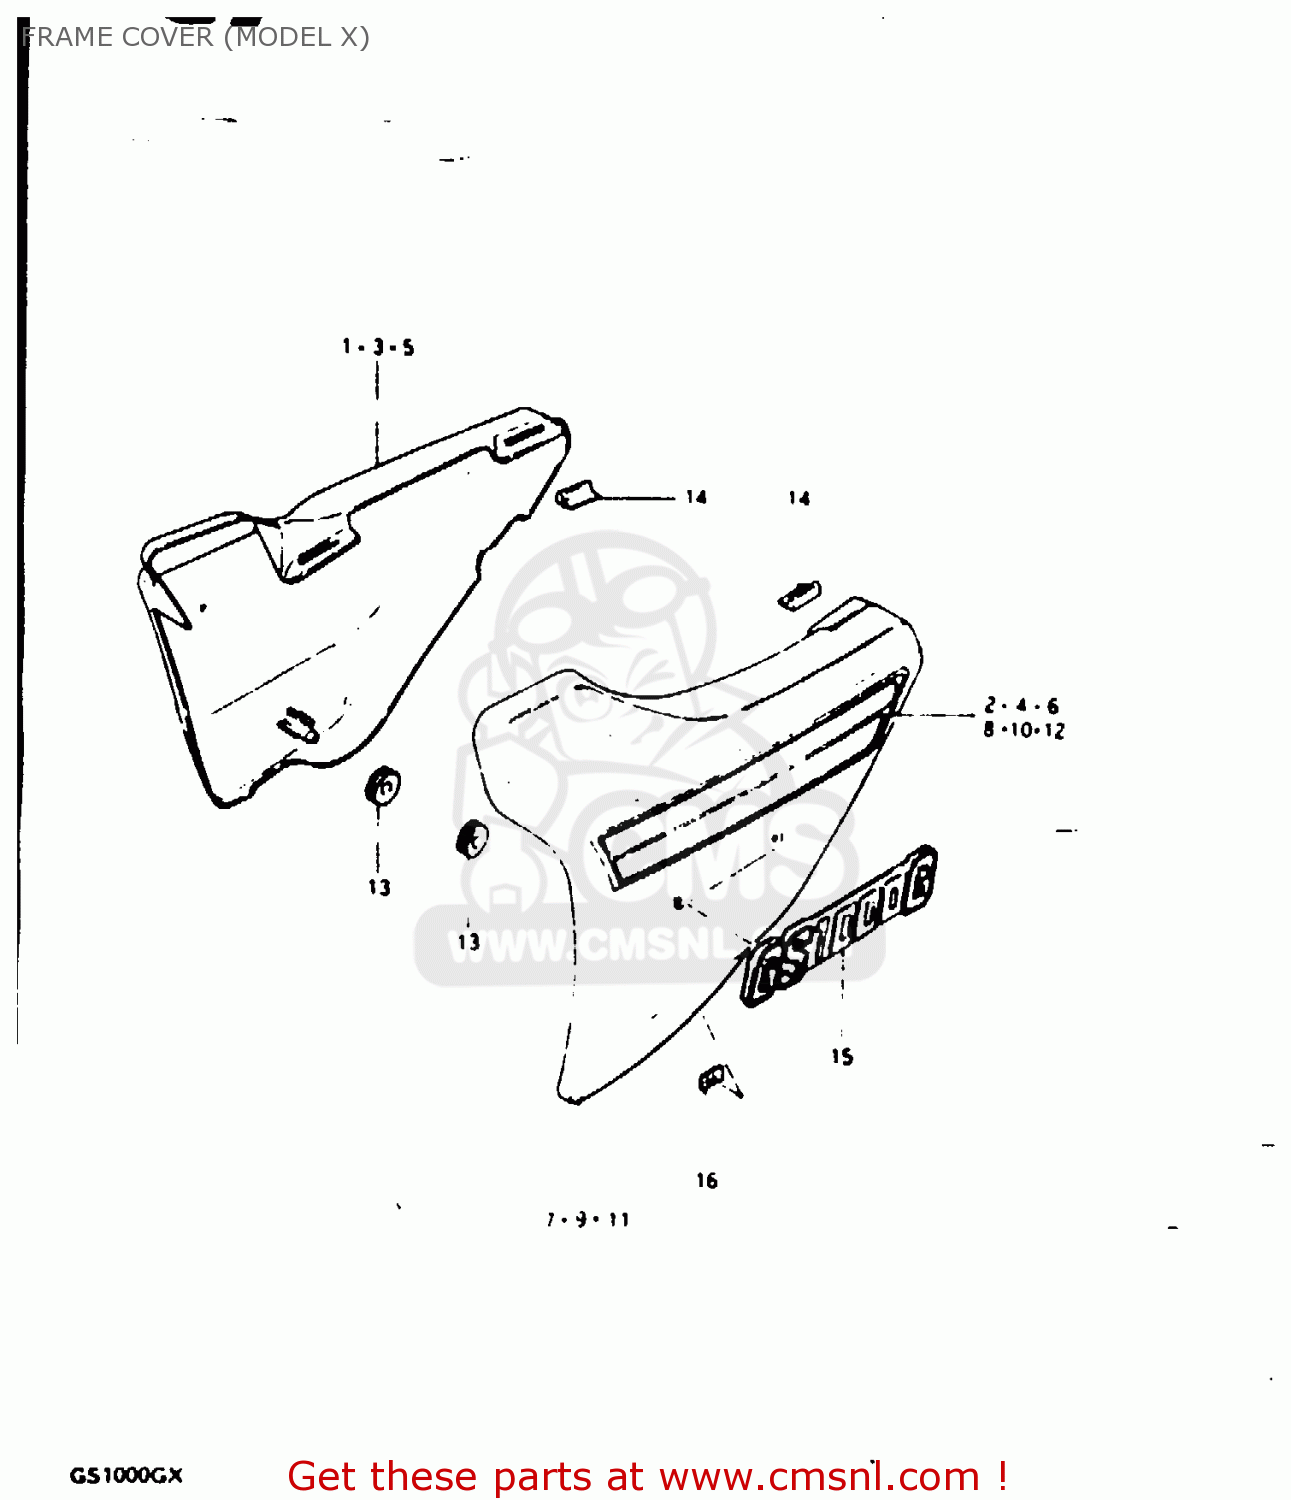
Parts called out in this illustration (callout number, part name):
1	COVER, FRAME RH (BLACK)
2	TAPE, RH
3	COVER, FRAME RH (RED)
4	TAPE, RH
5	COVER, FRAME RH (BLUE)
6	TAPE, RH
7	COVER, FRAME LH (BLACK)
8	TAPE, LH
9	COVER, FRAME LH (RED)
10	TAPE, LH
11	COVER, FRAME LH (BLUE)
12	TAPE, LH
13	CUSHION
14	CUSHION,FRAME COVER
15	EMBLEM,FRAME COVER
16	NUT
